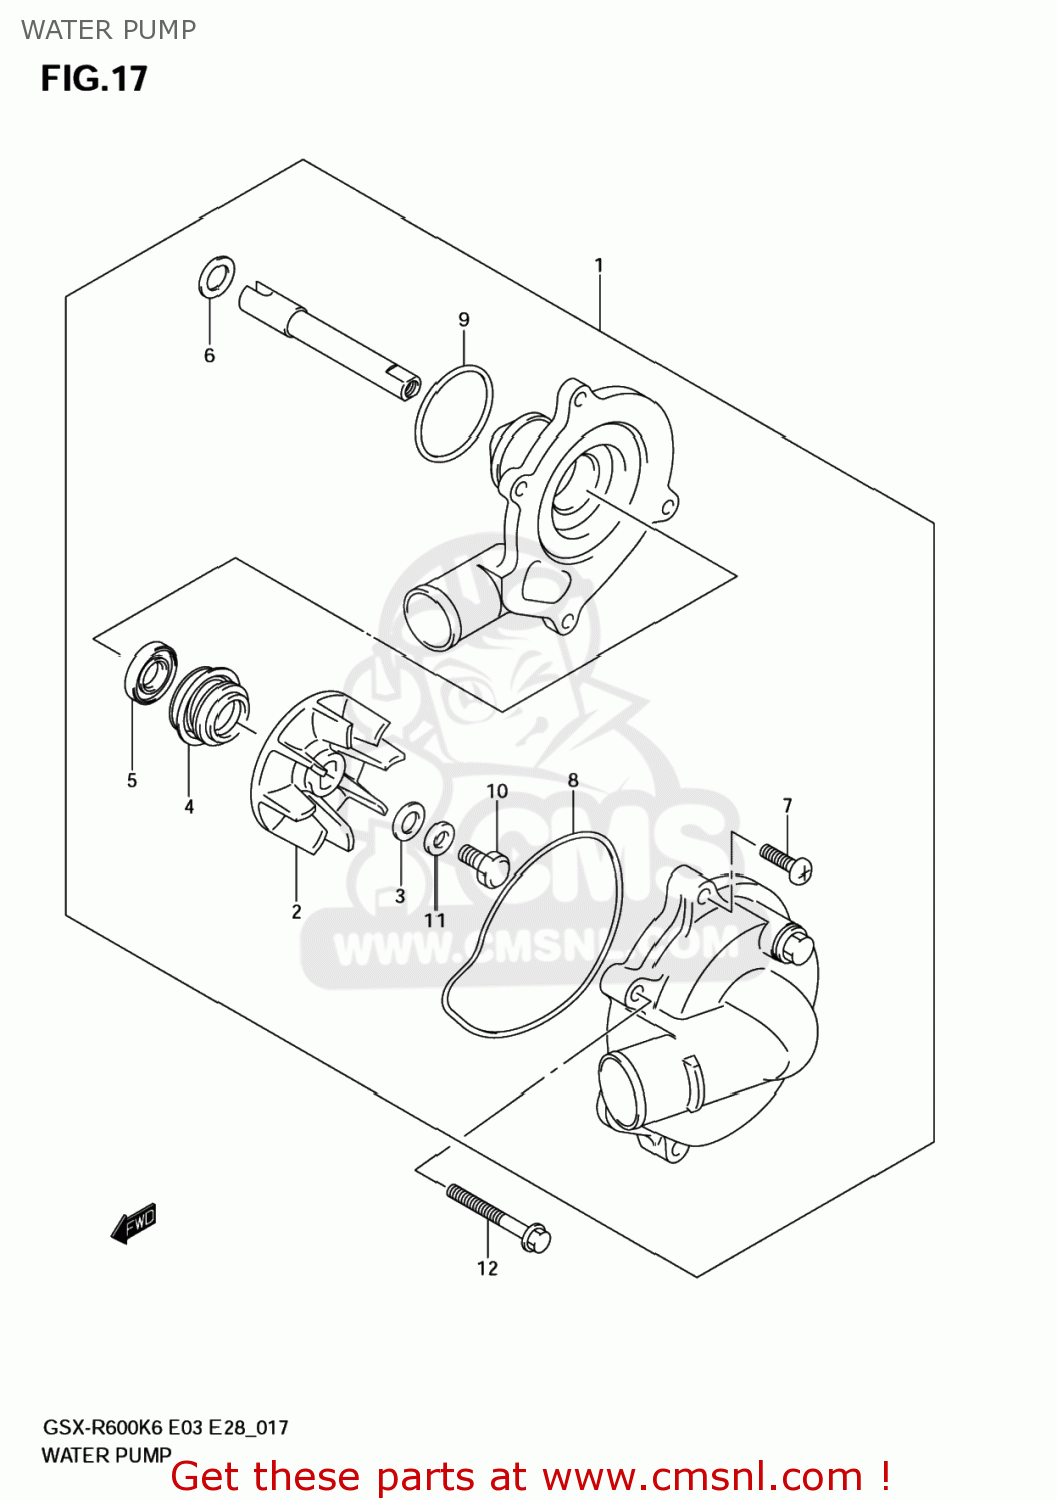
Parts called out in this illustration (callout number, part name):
1	PUMP ASSY,WATE
2	IMPELLER
3	GASKET(6X15X2.2) (NAS)
4	SEAL,MECHANICAL
5	SEAL,OIL
6	SHIM(10X18X1)
7	SCREW 6X16
8	O RING
9	O RING,WATER PUMP HOLDER
10	BOLT(6X13)
11	WASHER
12	BOLT
